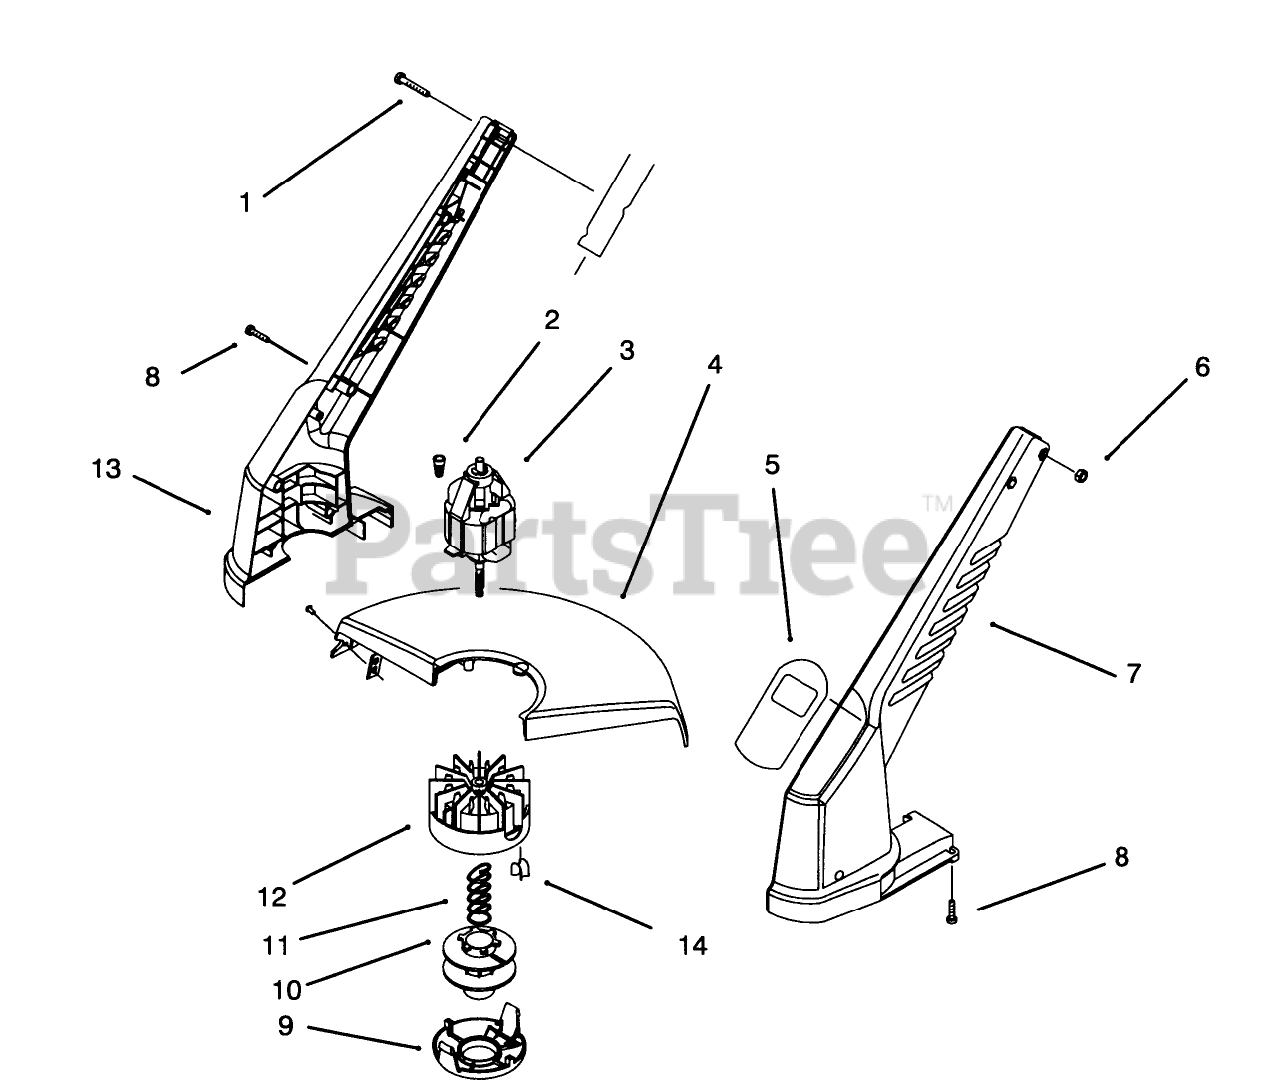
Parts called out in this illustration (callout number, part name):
1	SCREW-PPH
2	CONNECTOR-NUT, WIRE
3	Motor Assembly (Incl. Ref. #12 &-14)
4	SHIELD ASM - SERVICE
5	DECAL - 14" TRIMMER
6	NUT-HEX
7	LH HOUSING
8	Screw
10	SPOOL-LARGE
11	SPRING-COMPRESSION
12	Drum
13	RH HOUSING
14	EYELET
